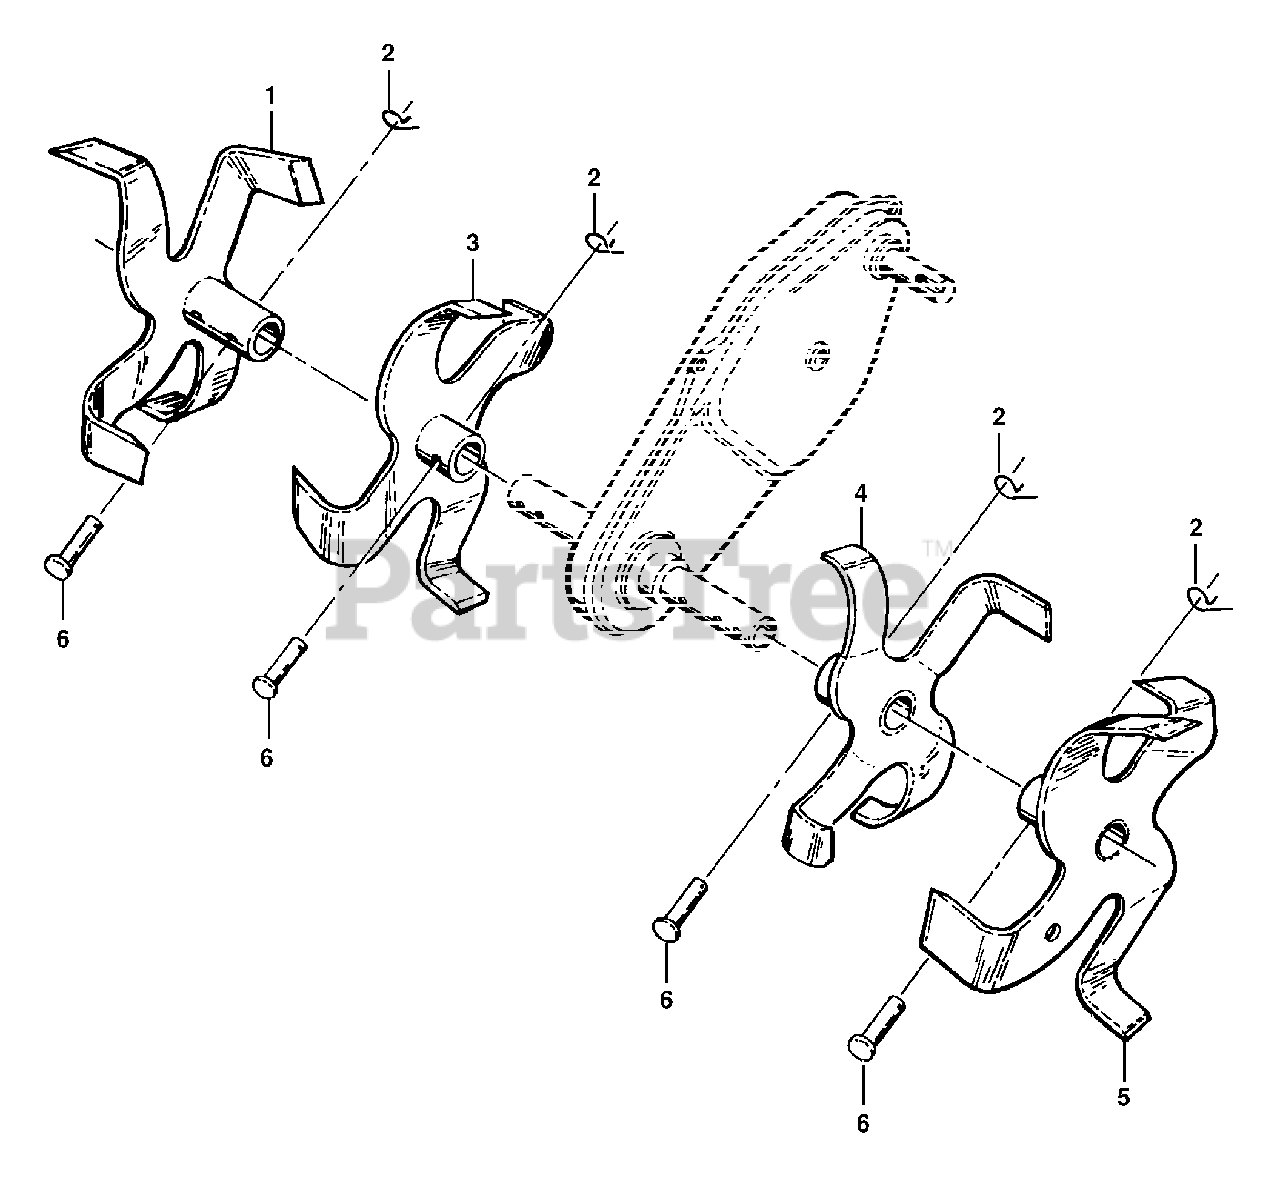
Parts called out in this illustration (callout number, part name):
1	Tine, Outer, R.H.
2	Retainer Spring
3	Tine, Inner, R.H.
4	Tine, Inner, L.H.
5	Tine, Outer, L.H.
6	Pin, Clevis
